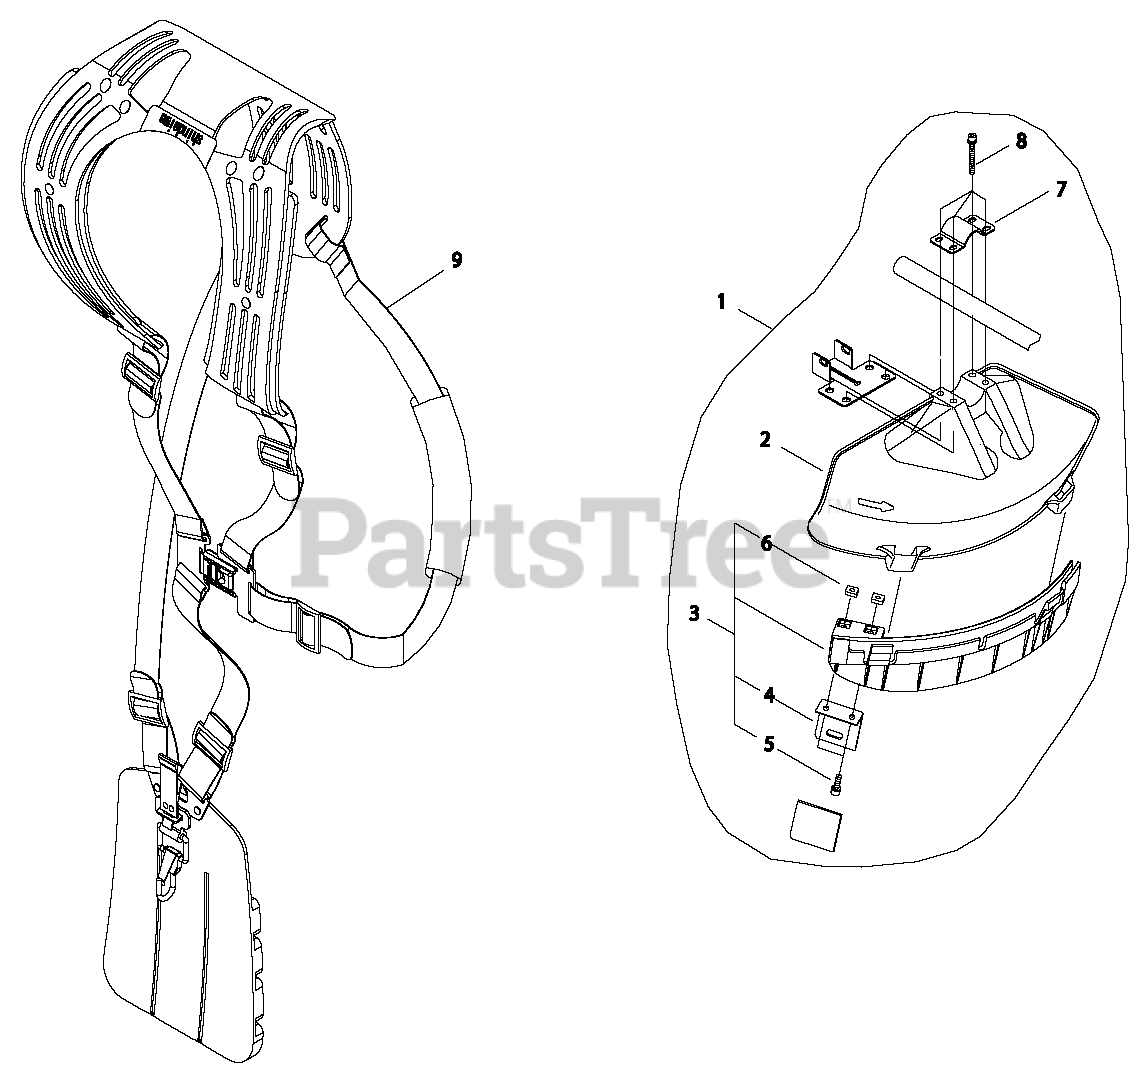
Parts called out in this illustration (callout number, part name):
1	DEBRIS SHIELD KIT
2	SHIELD, DEBRIS
3	SHIELD GUARD KIT
4	KNIFE, TRIMMER LINE
5	SCREW - 5X16
6	NUT - 5
7	CLAMP - UPPER
8	SCREW - 5X45
9	HARNESS ASSY
